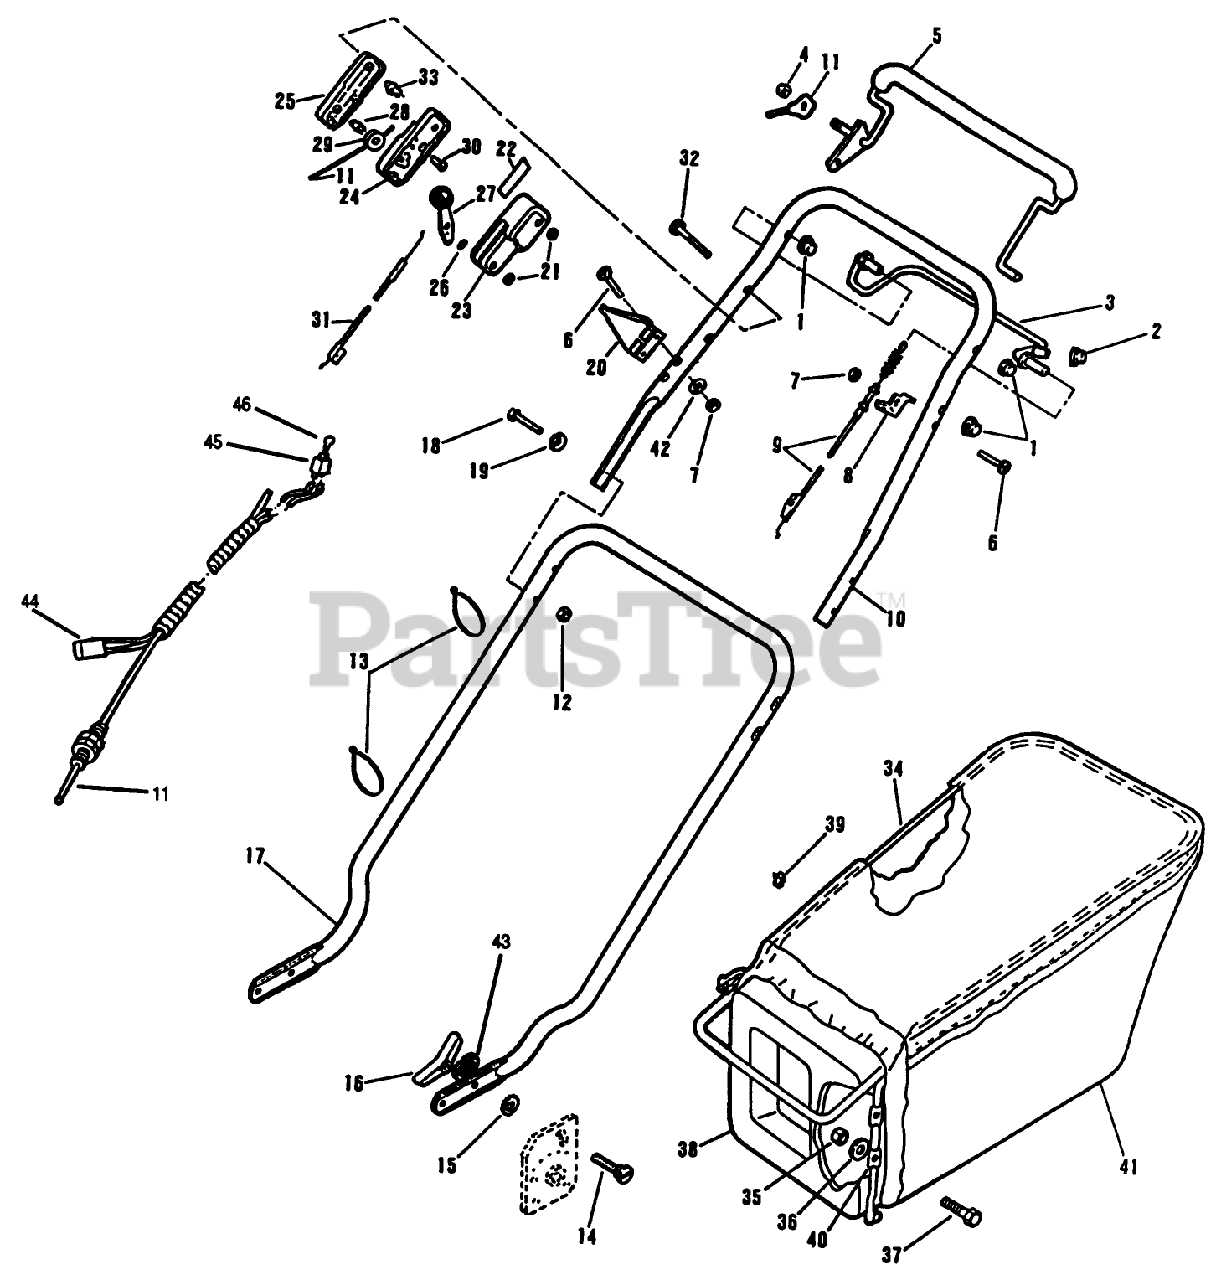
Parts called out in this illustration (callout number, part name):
4	NUT ACORN
5	CONTROL LEVER ARG
7	LOCKNUT E
8	ANCHOR C'DUIT TRO
9	CONTROL CABLE WES
11	CONTROL CABLE
12	NUT-LOCK F
13	TIE-CABLE
16	NUT-WING
17	LOWER HANDLE *G
19	WASHER-CURVED
21	NUT C/LOCK E
25	OUTER CONTROL CASE
26	WASHER-SPRING
27	LEVER&KNOB AY WES
28	PIN SKF
29	PULLEY PL
30	SCREW
31	T/CABLE WESCON
32	SCREW
33	COLUMN
34	HANGER BAG TROX
35	LOCKNUT E
36	WASHER
38	BAG ADAPTOR PL
39	S CLIP ARDEN
40	LATCH BAR AY ARGO
42	WASHER
